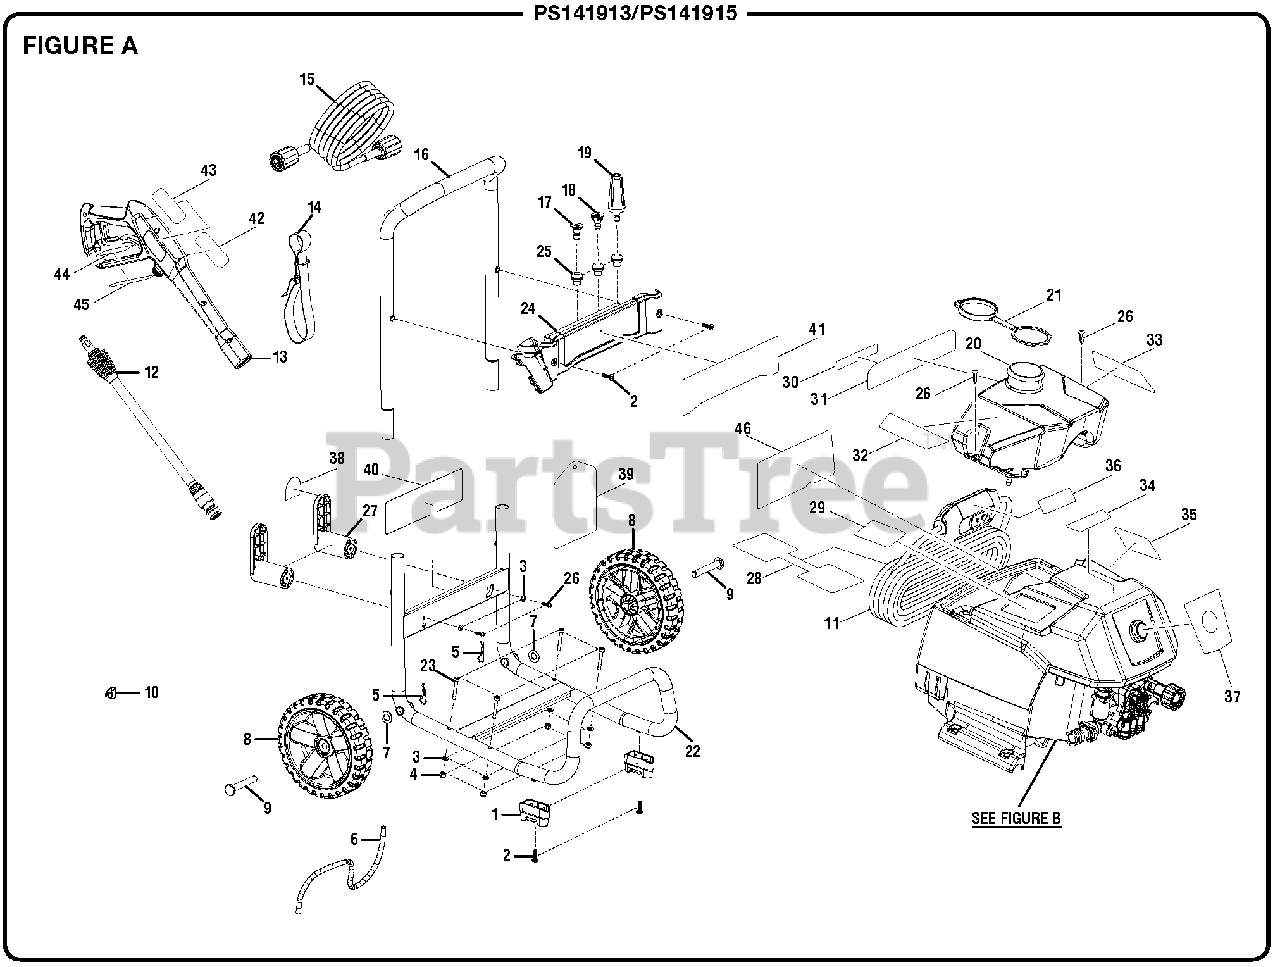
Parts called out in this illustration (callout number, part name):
2	Bolt (M6 x 20 mm, Pan Hd.)
3	Washer (M6)
4	Lock Nut (M6)
5	Hitch Pin
6	Suction Hose
7	Washer (ID12.5 x OD24 x 2t)
10	Cord Clip
11	Power Cord
12	Spray Wand
13	Trigger Handle
14	Hose Storage Strap
15	Hose (25 ft.) [PS141913]
16	Handle Assembly
17	Soap Nozzle
18	Nozzle (15deg)
19	Turbo Nozzle
20	Detergent Tank (PS141913)
20	Detergent Tank (PS141955)
21	Detergent Tank Cap
23	Bolt (M6 x 40 mm Hex. Soc. Hd.)
24	Front Panel
25	Nozzle Grommet
26	Screw (M4.8 x 19 mm, Pan Hd.)
27	Cord Wrap Arm
28	Cord Wrap Label
29	Vent Label (Left)
30	Inquires Label
31	Quick Start Label (PS141913)
31	Quick Start Label (PS141955)
32	Nozzle Select Label (PS141913)
32	Nozzle Select Label (PS141955)
33	Detergent Tank Label (PS141913)
33	Detergent Tank Label (PS141955)
34	Logo Label
35	Vent Label (Right)
36	Cord Plug Label
37	On/Off Switch Label (PS141913)
37	On/Off Switch Label (PS141955)
38	Cord Unlock Label
39	Nozzle Hangtag (PS141913)
40	Regulatory Label (PS141913)
40	Regulatory Label (PS141955)
41	Performance Label (PS141913)
41	Performance Label (PS141955)
42	Trigger Handle Warning Label (English)
43	Trigger Hanlde Logo Label
44	Trigger Handle Warning Label (French/Spanish)
45	Trigger Handle Rating Label
46	Danger Icon Label (PS141955)
